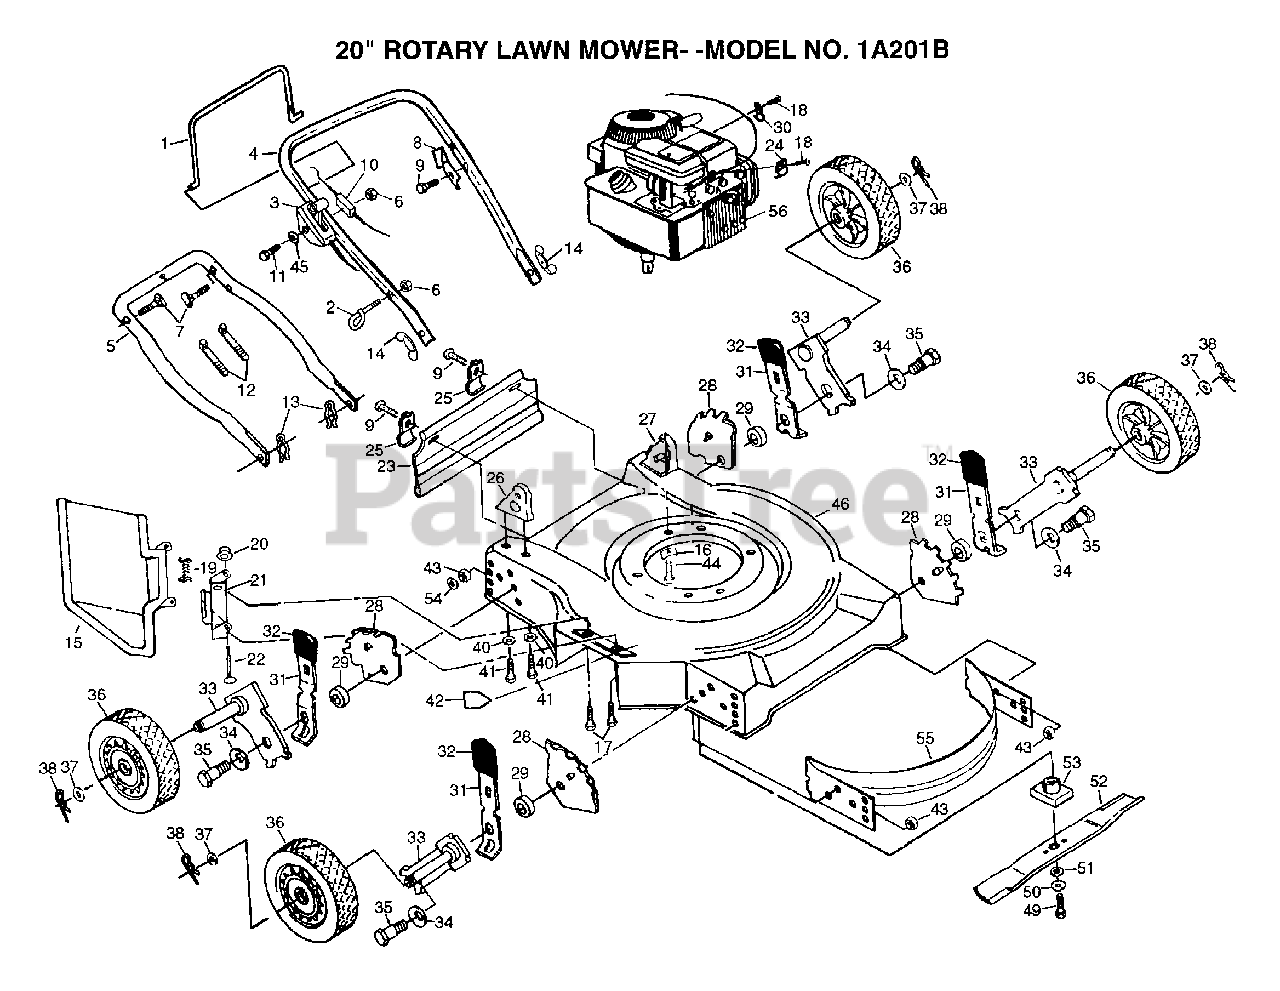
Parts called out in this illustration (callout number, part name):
1	CONTROL BAR PM
2	ROPE GUIDE
3	CONTROL THROTTLE
7	BOLT.HANDLE.LM
8	"BRKT,UPSTOP"
9	TAPPING SCREW
10	"CABLE,ENG ZONE CO"
13	HAIRPIN COTTER
14	"NUT,WING PM"
15	"GRD,DISCHARGE"
17	SCREW
18	SCREW PM
19	"SPRING,TORSION"
20	PUSH ON SPEED NUT
21	"BRKT,HSG "
24	CABLE CLAMP
25	"BRKT,DEFL PM"
30	GUIDE CLIP PM
32	KNOB PM
33	AXLE ARM
34	"WASHER, BELLEVIL."
36	WHEEL ASSY
37	WASHER
38	RETAINER CLIP PM
40	STEEL WASHER
41	SCREW
42	DECAL HYT
43	LOCKNUT PM
44	SCREW
45	WASHER PM
46	"KIT.HSG.20""SDPUSH"
49	SCREW
50	LOCKWASHER
51	"WASHER,HARDEN"
52	BLADE.STAND.20INC
53	BLADE ADAPTOR
